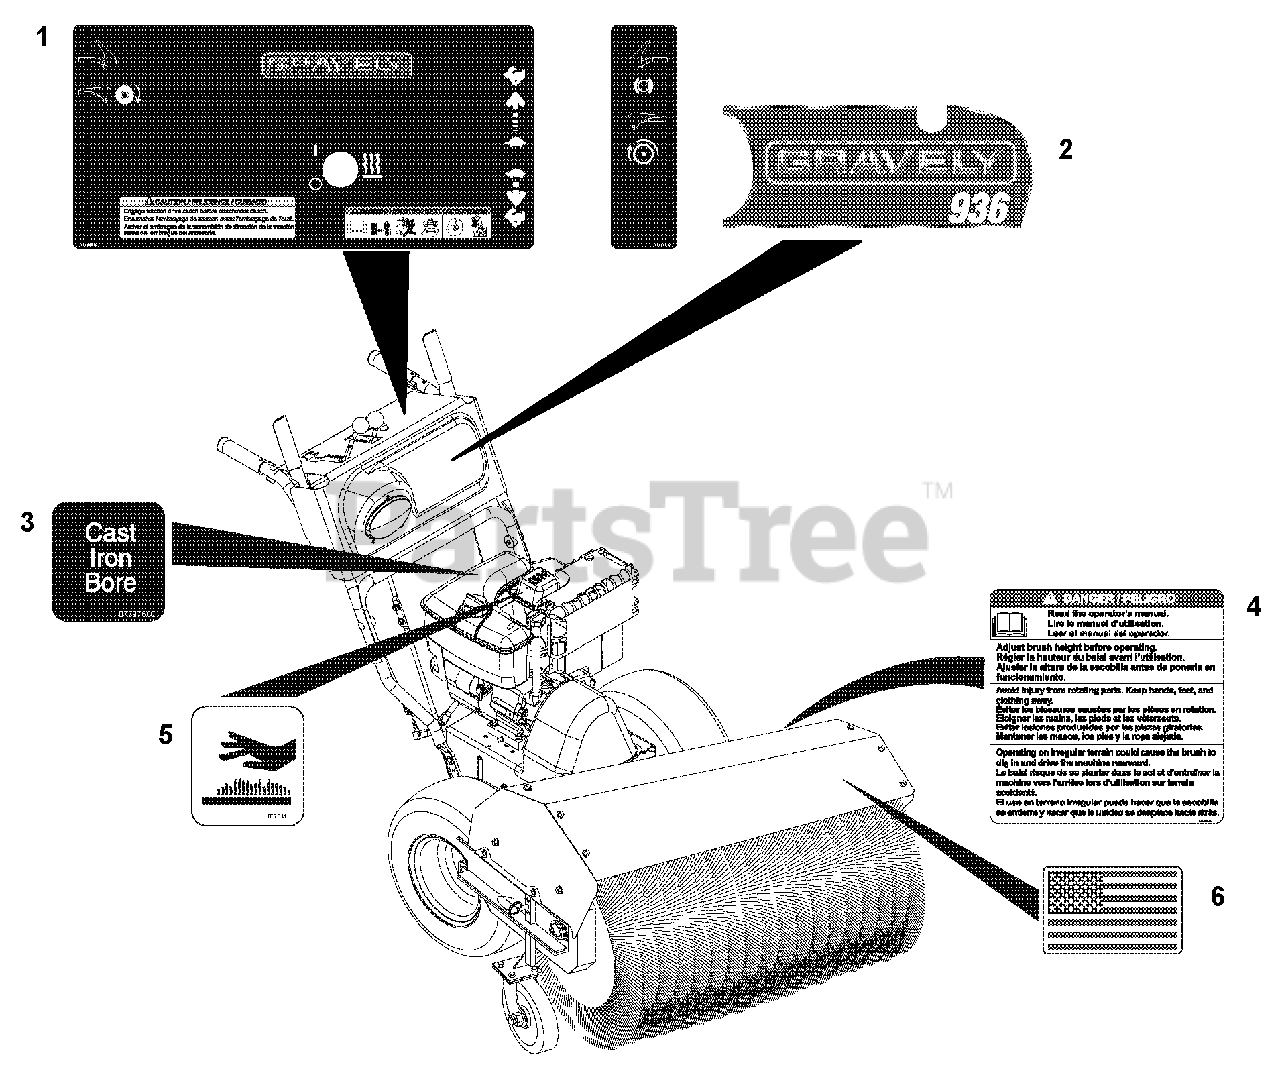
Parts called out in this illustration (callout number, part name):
1	Decal, Control-Gravely PB
2	Decal, Front Dash-Gravely Brush
3	Decal, Cast Iron Bore
4	Decal, Danger
5	Decal, Hot Surface
6	Decal, American Flag
